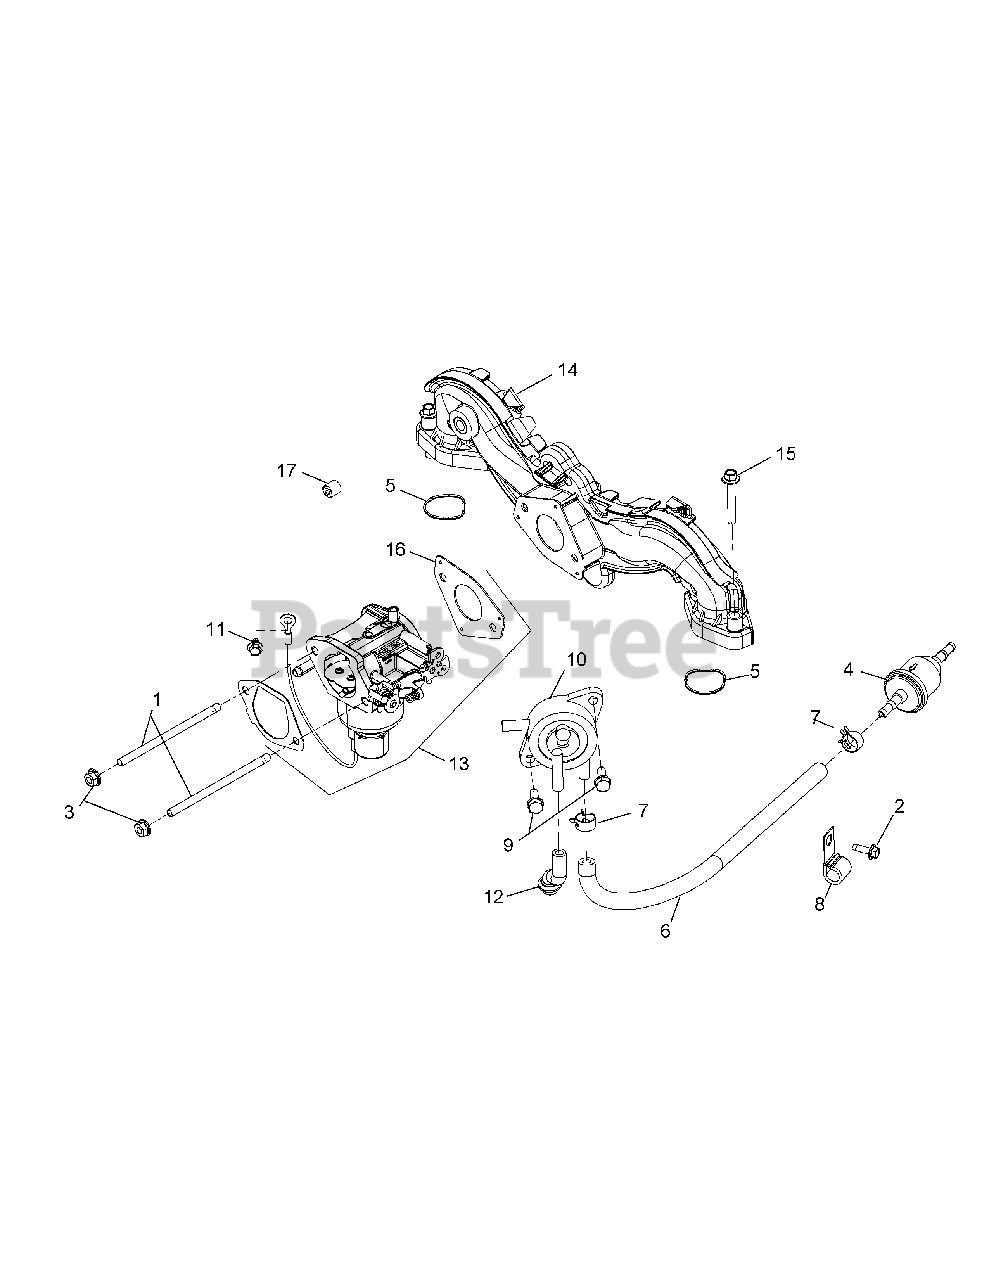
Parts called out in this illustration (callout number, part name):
2	Thread Forming Screw
3	Flange Nut, M6 x 1.0
5	Intake Port O-Ring
6	Fuel Line, 24"
7	Spring Hose Clamp
9	Tap Screw, M6 x 1.7 x 18
11	Thread Forming Screw
12	Pulse Pump Hose
13	Carburator Kit
14	Intake Manifold Kit
15	Flange Screw, M6 x 1.0 x 40
16	Carburetor Gasket
17	Pipe Plug, 1/8
